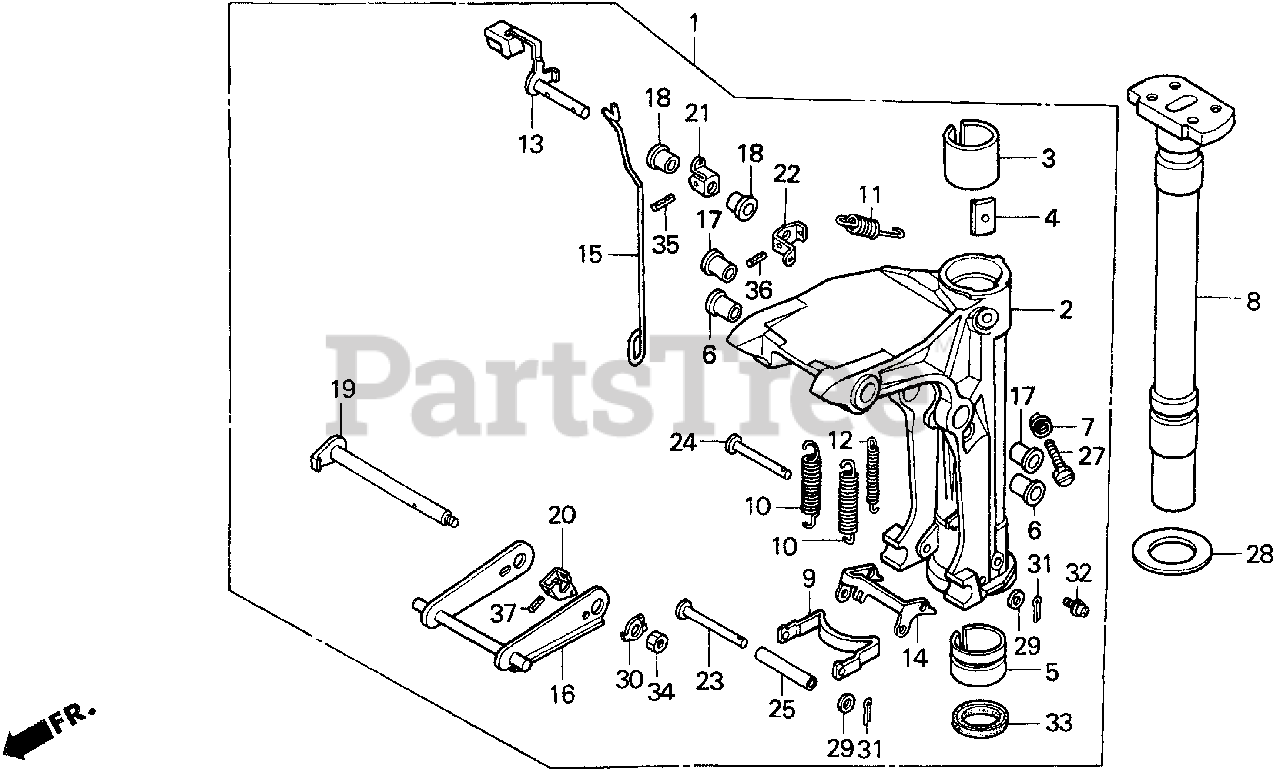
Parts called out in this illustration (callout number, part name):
1	CASE ASSY., SWIVEL *NH282MU* (OYSTER SILVER METALLIC-U)
2	CASE, SWIVEL *NH282MU* (OYSTER SILVER METALLIC-U)
3	LINER, SWIVEL CASE
4	BLOCK, FRICTION
5	BUSH, SWIVEL SHAFT
6	BUSH, SWIVEL CASE
7	SPRING, FRICTION ADJUSTING
8	SHAFT, SWIVEL *NH282MU* (OYSTER SILVER METALLIC-U)
9	HOOK, REVERSE LOCK
10	SPRING, REVERSE LOCK
11	SPRING, TILT LEVER
12	SPRING, TILT LINK
13	LEVER, TILT
14	ARM, REVERSE LOCK
15	ROD, RELEASE SWIVEL CASE
16	ARM, TILT
17	BUSH, TILT LEVER
18	BUSH, TILT LEVER
19	SHAFT, TILT
20	BRACKET, TILT SHAFT
21	BRACKET, RELEASE ROD
22	BRACKET, TILT LEVER
23	SHAFT, REVERSE LOCK (A)
24	SHAFT, REVERSE LOCK (B)
25	COLLAR, REVERSE LOCK
27	BOLT, SPECIAL (8X20)
28	WASHER, THRUST
29	WASHER, PLAIN (6MM)
30	WASHER, LOCK
31	PIN, SPLIT
31	PIN, SPLIT (2.0)
32	NIPPLE, GREASE
33	OIL SEAL (32X37X7)
34	NUT, HEX. (6MM)
35	PIN, SPRING (3.0X22)
36	PIN, SPRING (3.0X25)
37	PIN, SPRING (3.0X25)
